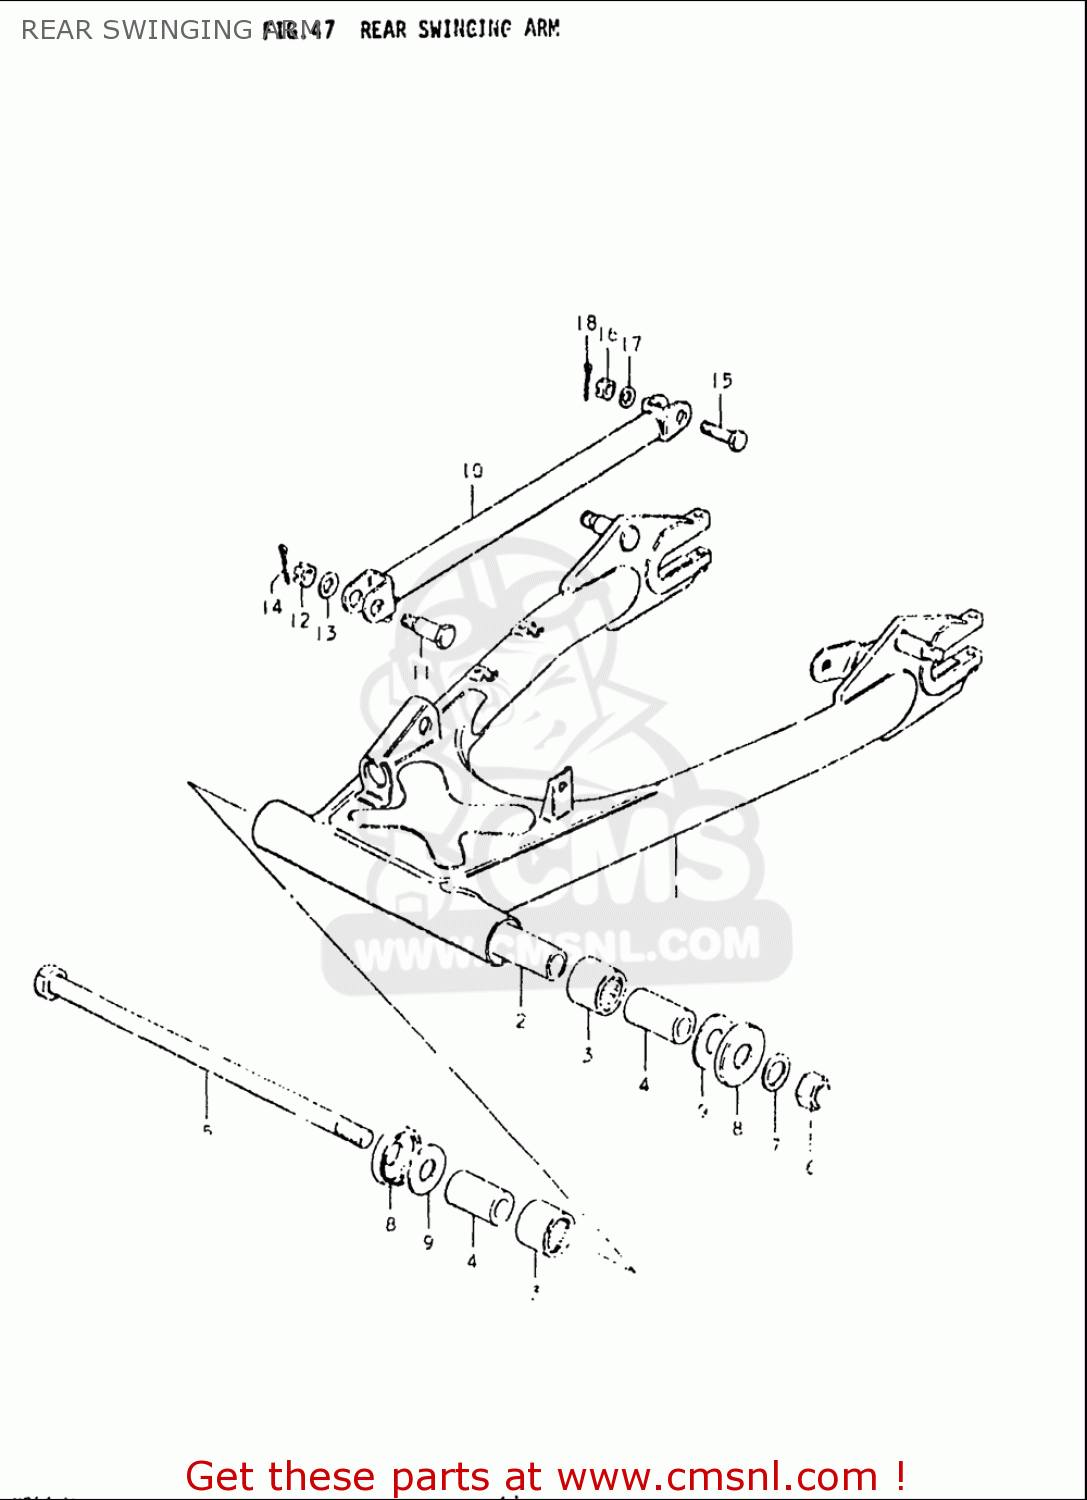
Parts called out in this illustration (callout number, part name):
2	SPACER,RR SWGARM PIVOT CTR
3	BEARING(22X29X30)
4	SPACER,RR SWGARM PIVOT
5	SHAFT,REAR SWING ARM
6	NUT 14MM
7	WASHER
8	CVR,RR SWGARM DUST SEAL(OD:40)
9	WASHER(14.2X34X1)
11	BOLT M10X39
12	NUT
13	WASHER
14	PIN
15	BOLT(10X39)
16	NUT
17	WASHER
18	PIN
